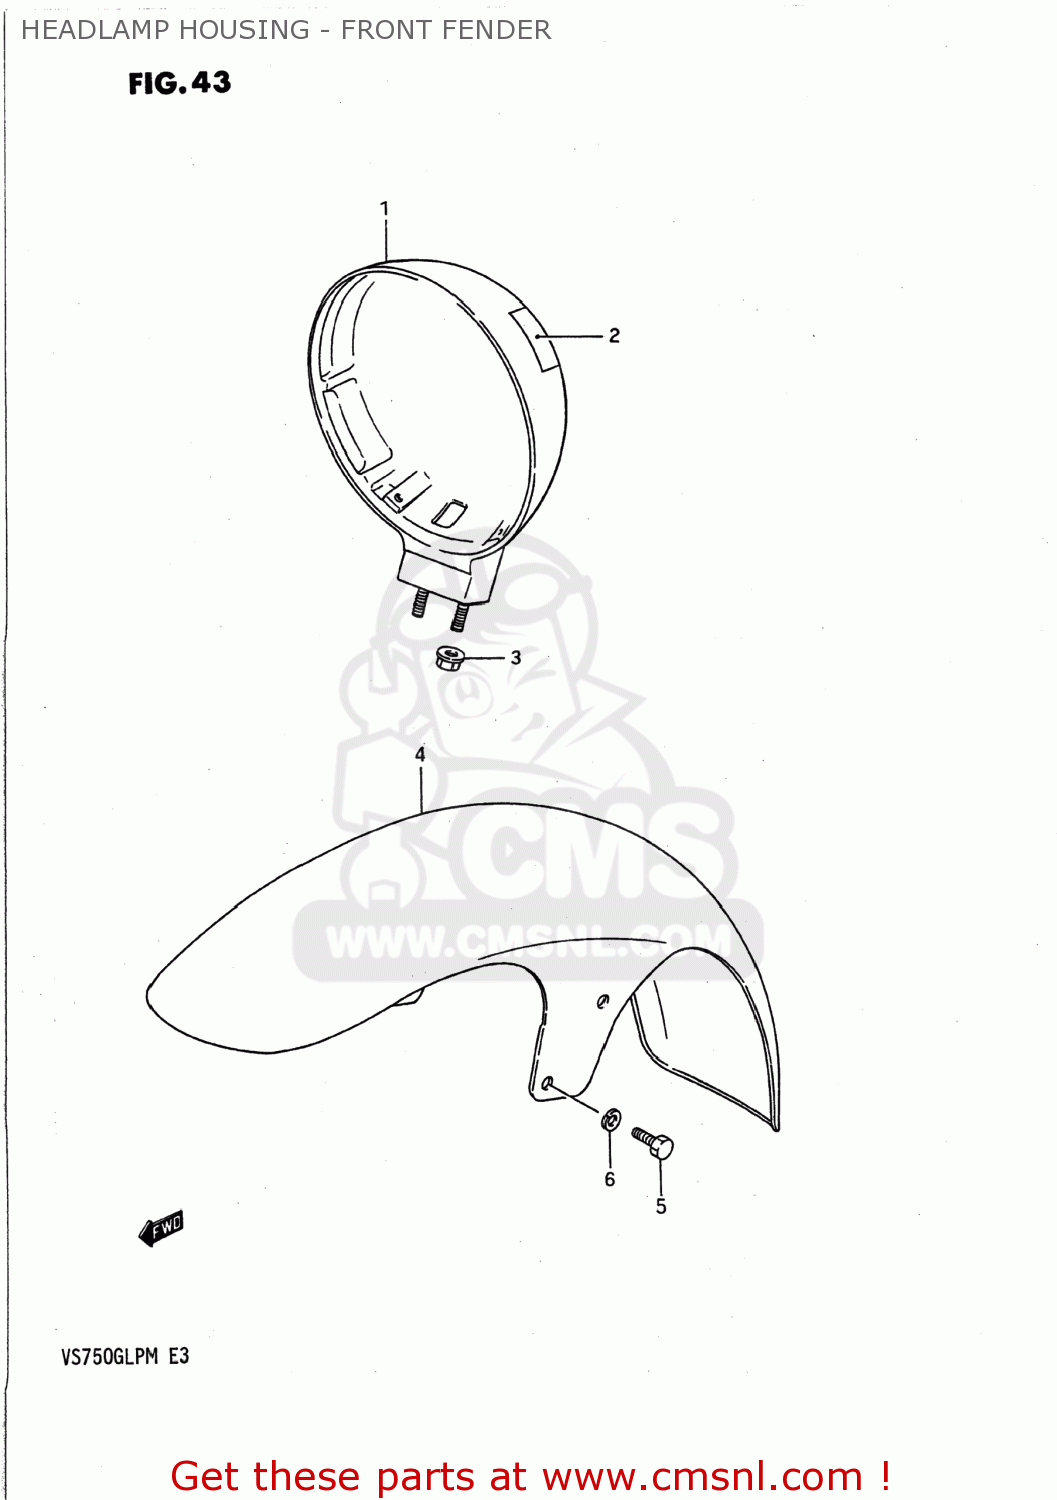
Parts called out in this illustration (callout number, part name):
1	HOUSING,HEADLAMP
2	TAPE,FRAME HEAD COVER
3	NUT
4	FENDER,FRONT
5	BOLT
6	WASHER,LOCK
